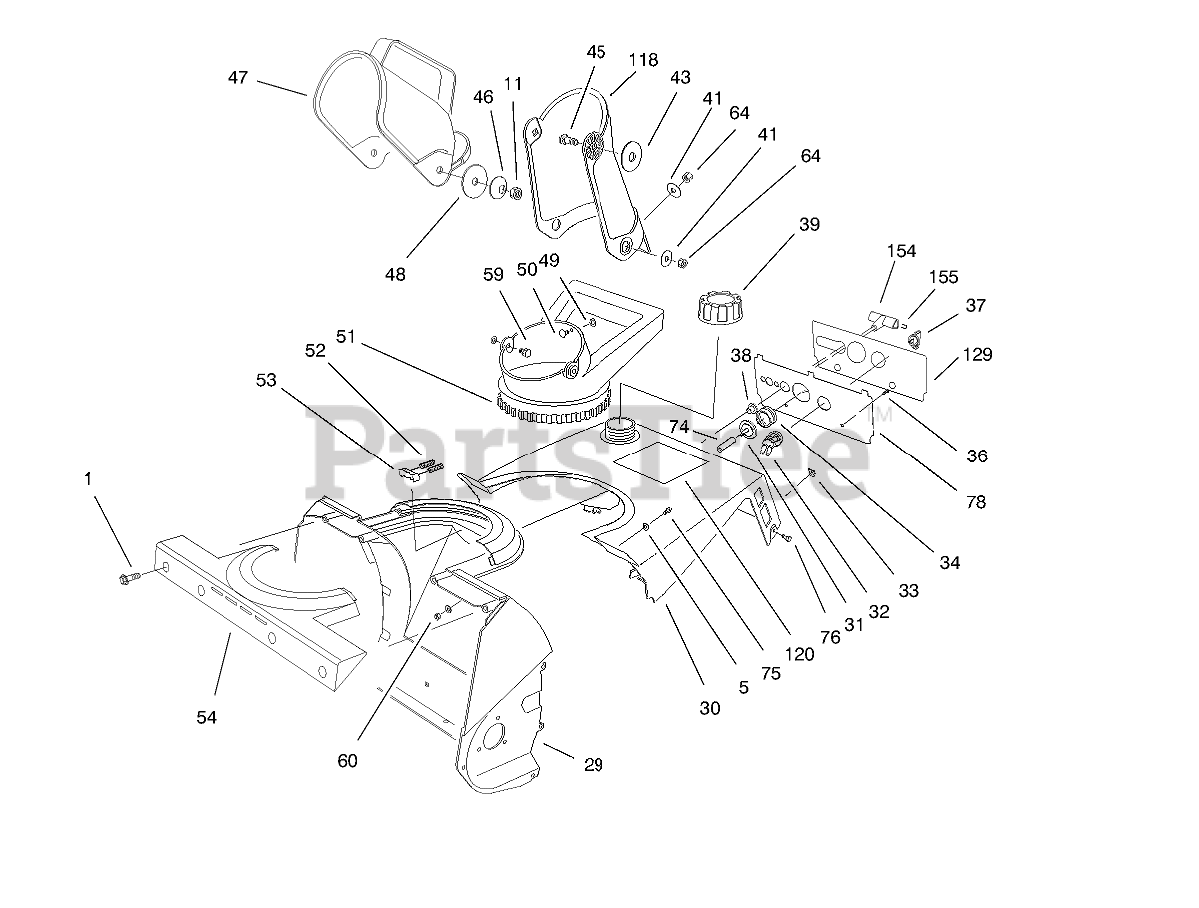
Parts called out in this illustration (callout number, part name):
1	SCREW-PLASTIC
5	WASHER-FLAT
11	NUT-LOCK, NI
29	HOUSING
30	Shroud-Upper
31	BODY-PRIMER
32	SWITCH
34	BULB-PRIMER
36	SCREW-SHWH, THREAD FORMING
37	KEY-IGNITION
38	GUIDE-ROPE, STARTER
39	CAP-FUEL ASM
41	WASHER-FLAT
43	Washer-Rubber
45	BOLT-CARR
46	WASHER-BELLEVILLE
47	DEFLECTOR-CHUTE
48	WASHER-FLAT
49	PUSHNUT-RETAINER, BOLT
50	SCREW-CARR
51	HANDLE-CHUTE
52	SPRING-COMPRESSION
53	DETENT-CHUTE
54	RETAINER-CHUTE
59	SCREW-HH
60	NUT-LOCK, NI
64	NUT-LOCK, NI
74	HOSE-PRIMER
75	SCREW-PPH
76	SCREW-THREAD FORMING
78	Panel-Control
118	CHUTE
120	DECAL - POWERLITE EL.
129	DECAL - CONTROL PANEL
154	HANDLE-STARTER
155	STAPLE-HANDLE
